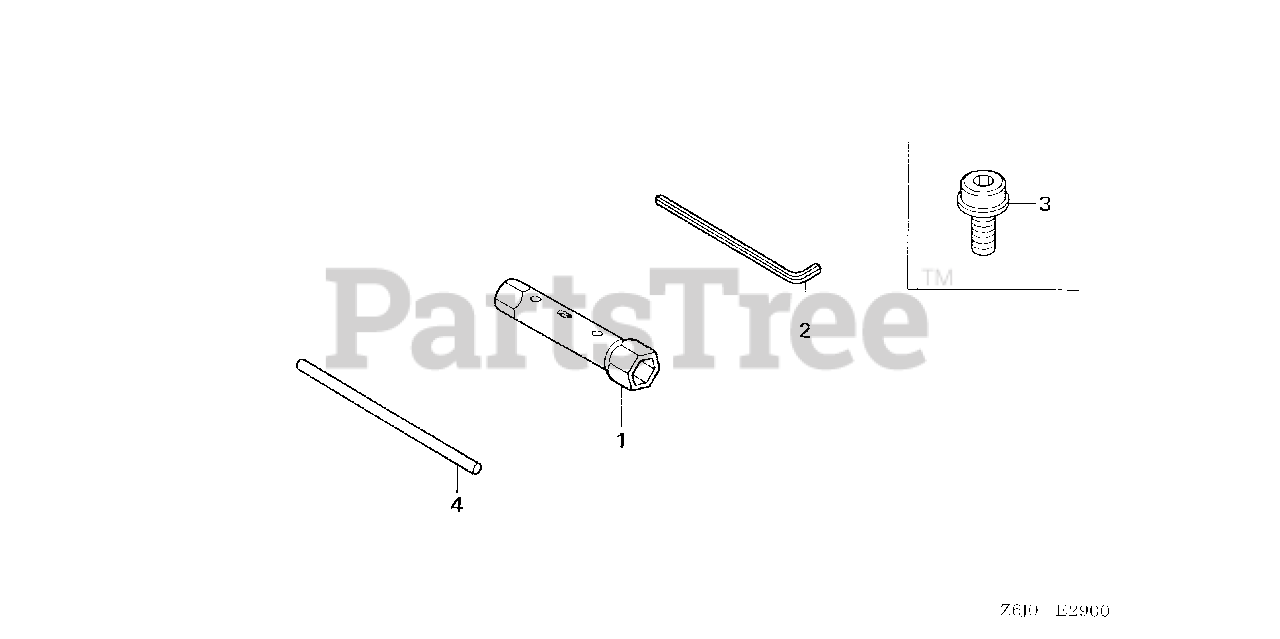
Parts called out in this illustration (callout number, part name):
1	WRENCH, PLUG (16X19)
2	WRENCH, HEX. (4MM)
4	BAR A, HANDLE
